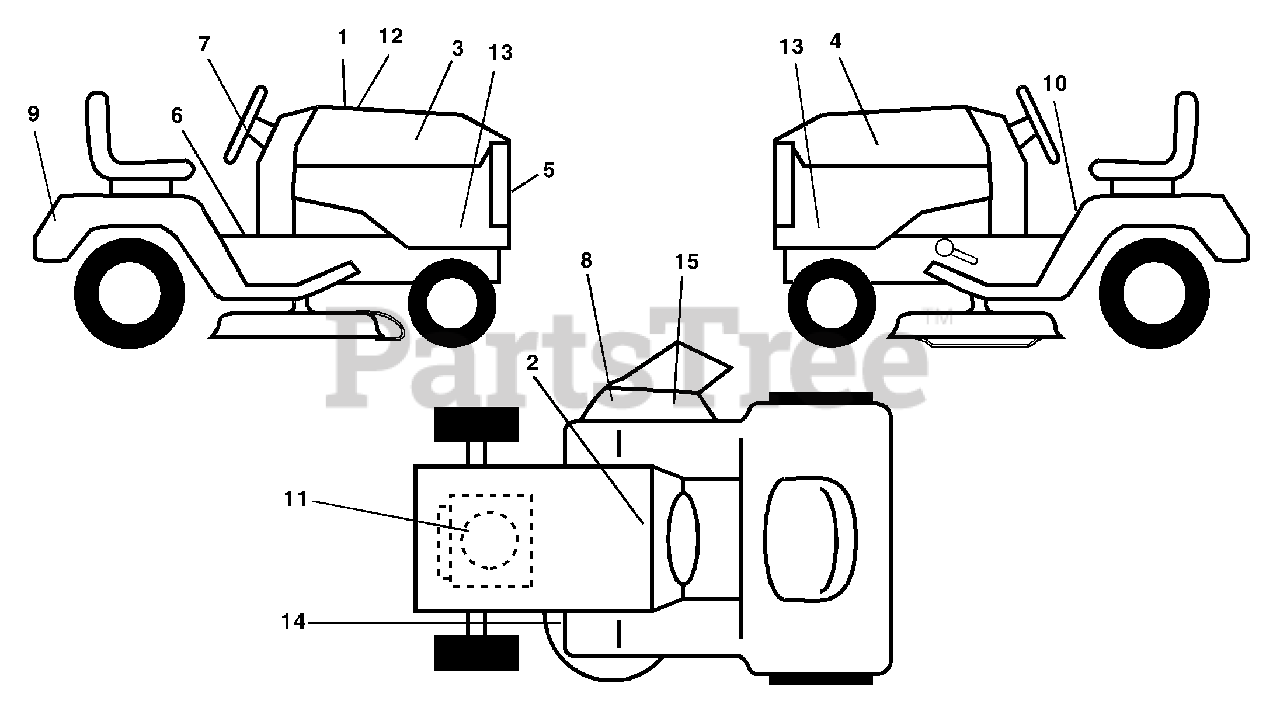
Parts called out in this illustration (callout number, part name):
1	Decal Hood Cust. Resp.
2	Decal Battery
3	Decal Hood RH
4	Decal Hood LH
5	Decal Grille
6	Decal Fender Oper
7	Decal Wheel Steering
8	Decal Warning
9	Decal Fender Husq
10	Decal Fender Danger E/F
11	Decal Engine
12	Decal Hood
13	Decal Hoodsides Kawa VTWN
14	Decal V-Belt Schematic
15	Decal Deck "B" 42"
